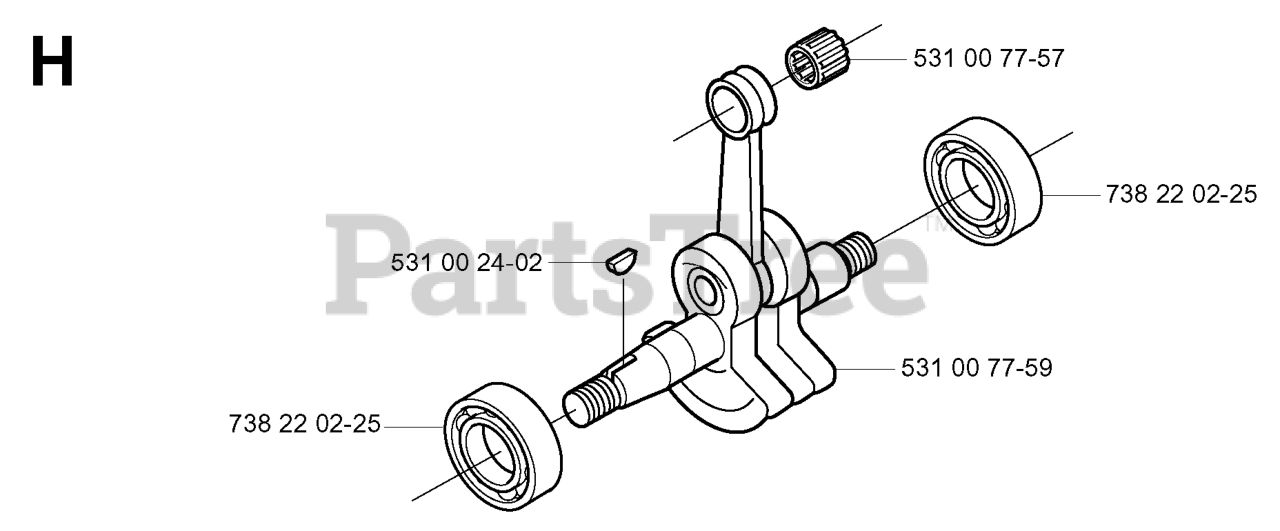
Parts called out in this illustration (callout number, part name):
1	REAR.WHEEL.TIRE.18X6.5X8.KENDA
2	TIRE.CASTER.ASSEM.11X4-5.GR
3	YOKE.CASTER.ORANGE
4	ZERK, 3/16, DRIVE IN
5	BUSHING, CASTER
7	SPACER, 5/16"
8	BEARING FLANGED
9	SPRING, CASTER
10	GREASE CAP
11	CASTER.PLUG
12	RHSNB 1/2-13 X 6.50 GR2 ZD
13	5/16-18X1 HHB G5W/NY
14	NUT 1/2-13 HEX NYLOC ZD
15	LUG NUT 1/2F
16	WASH USS FLAT 1/2
17	WASHER, 1.025 ID X 1.64
